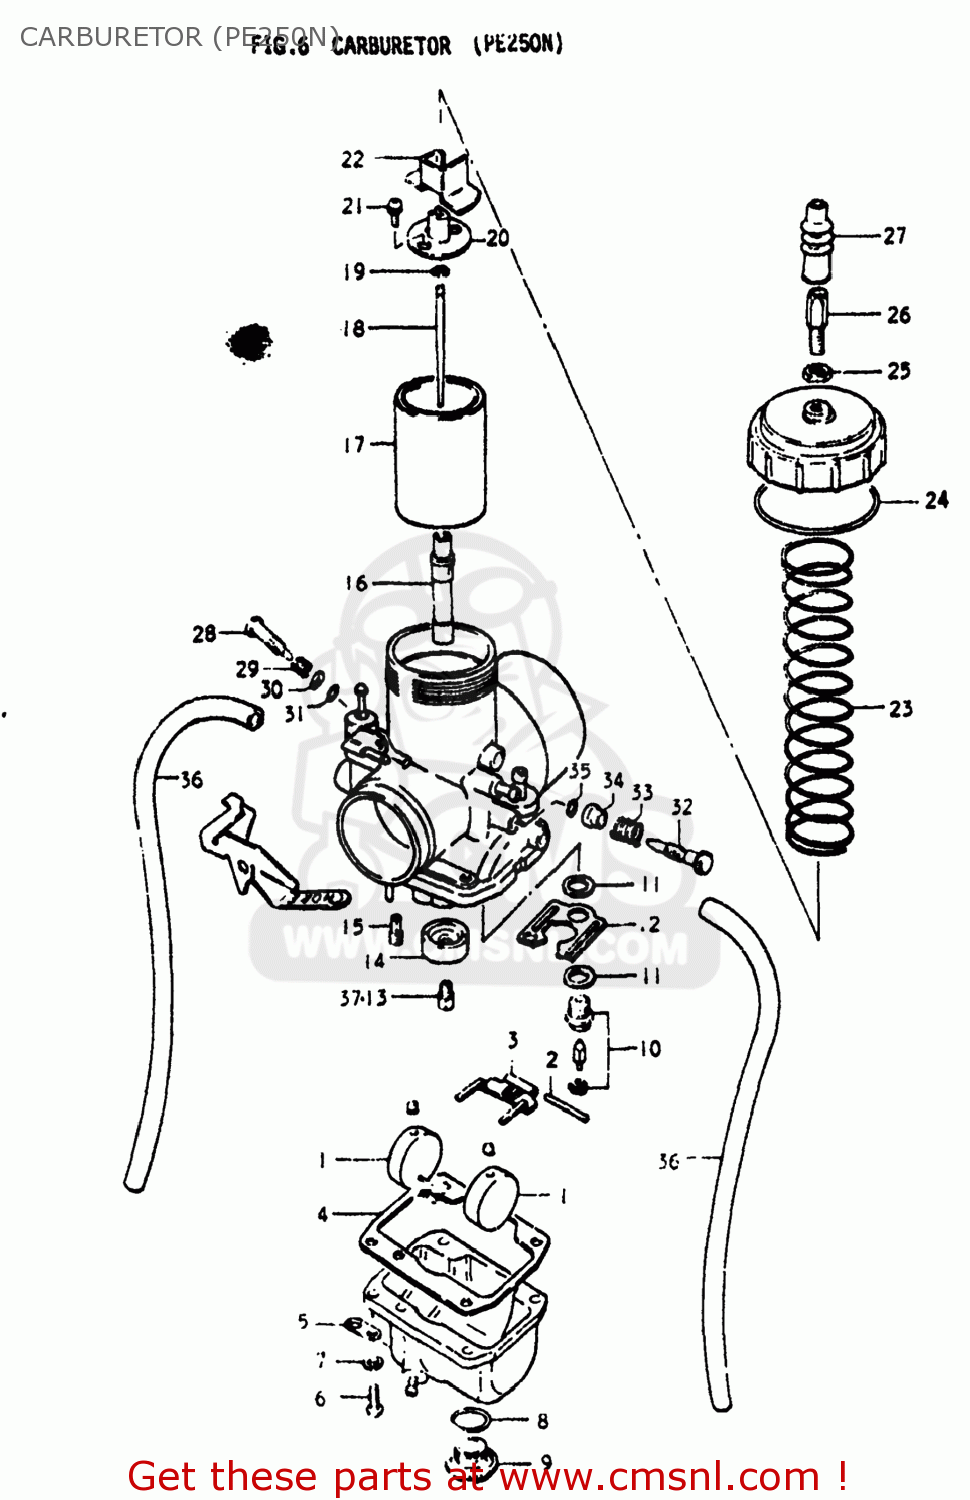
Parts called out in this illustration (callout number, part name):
1	FLOAT
2	PIN,FLOAT
3	ARM,FLOAT
4	GASKET,FLOAT CAHMBER (NAS)
5	PLATE
6	SCREW
7	LOCK WASHER
8	O-RING
9	SCREW,GUIDE
10	VALVE ASSEMBLY,NEEDLE
11	GASKET,MAIN JET HOLDER (NAS)
12	PLATE
13	JET
14	RING
15	JET,PILOT(40)
16	JET,NEEDLE
17	VALVE,THROTTLE
18	NEEDLE JET
19	CLIP
20	CONNECTOR
21	SCREW
22	COVER,HOLDER
23	SPRING,THROTTLE VALVE RETURN
24	GASKET,MIXING CHAMBER (NAS)
25	NUT
26	ADJUSTER,CABLE
27	CAP,CABLE ADJUSTER
28	PLATE
29	SPRING
30	WASHER,PILOT AIR SCREW
31	O RING
32	SCREW,THROTTLE STOP
33	SPRING,THROTTLE STOP
34	COVER
35	O-RING
36	HOSE
37	JET
